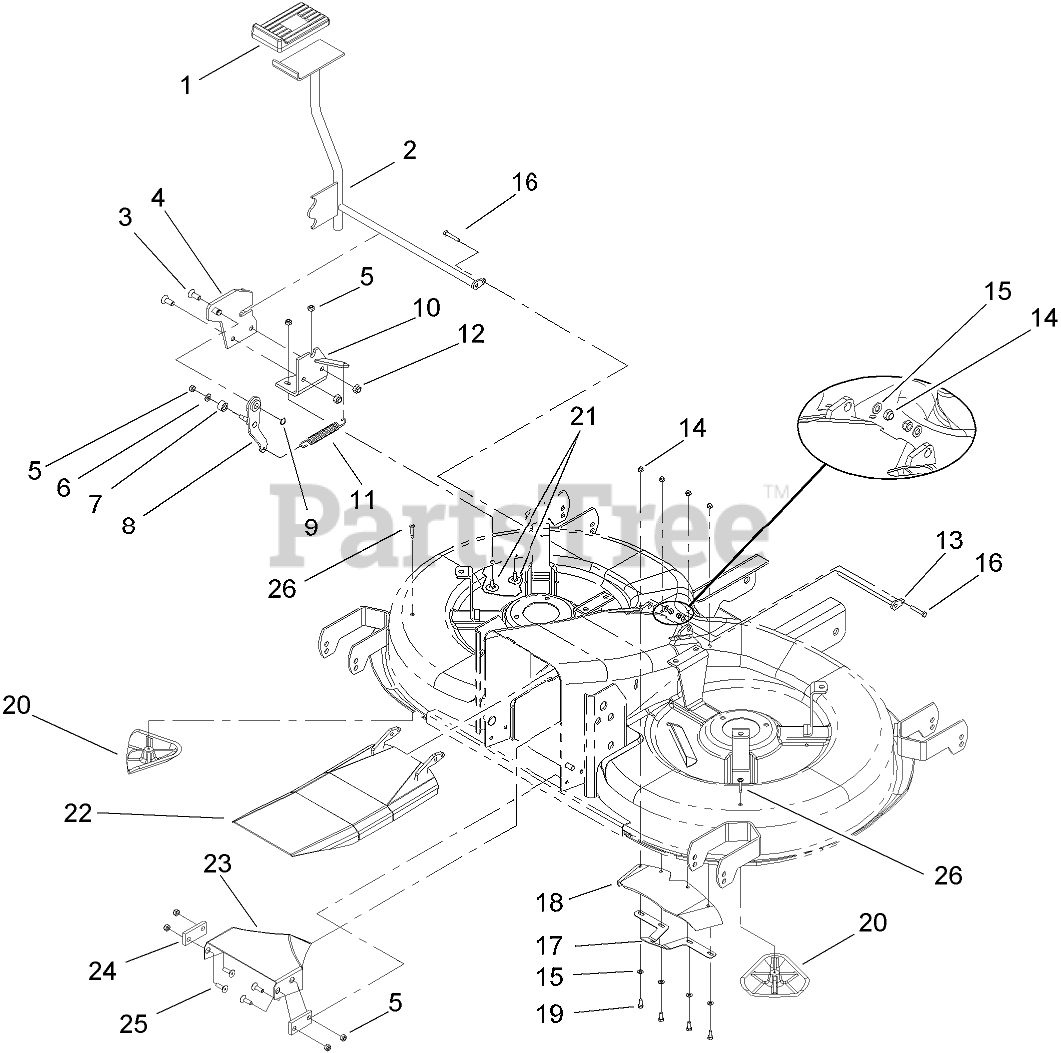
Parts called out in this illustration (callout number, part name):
1	Cover-Lever, FOOT
2	Lever-Foot
3	SCREW-HSFH
4	Plate-Stop
5	NUT-LOCK
6	WASHER-FLAT
7	Roller
8	Lever-Spring
9	RING-LOCKING
10	Bracket-Mounting
11	Spring
12	NUT
13	Rod-Door, Mulch
14	NUT-LOCK
15	WASHER
18	Gasket-Door, Mulch
19	Screw-HH
20	Kicker
21	SCREW-CARR
22	DOOR-MULCH
23	Baffle-Center
24	PLATE-BAFFLE, CENTER
26	SCREW-TAP, PPH
